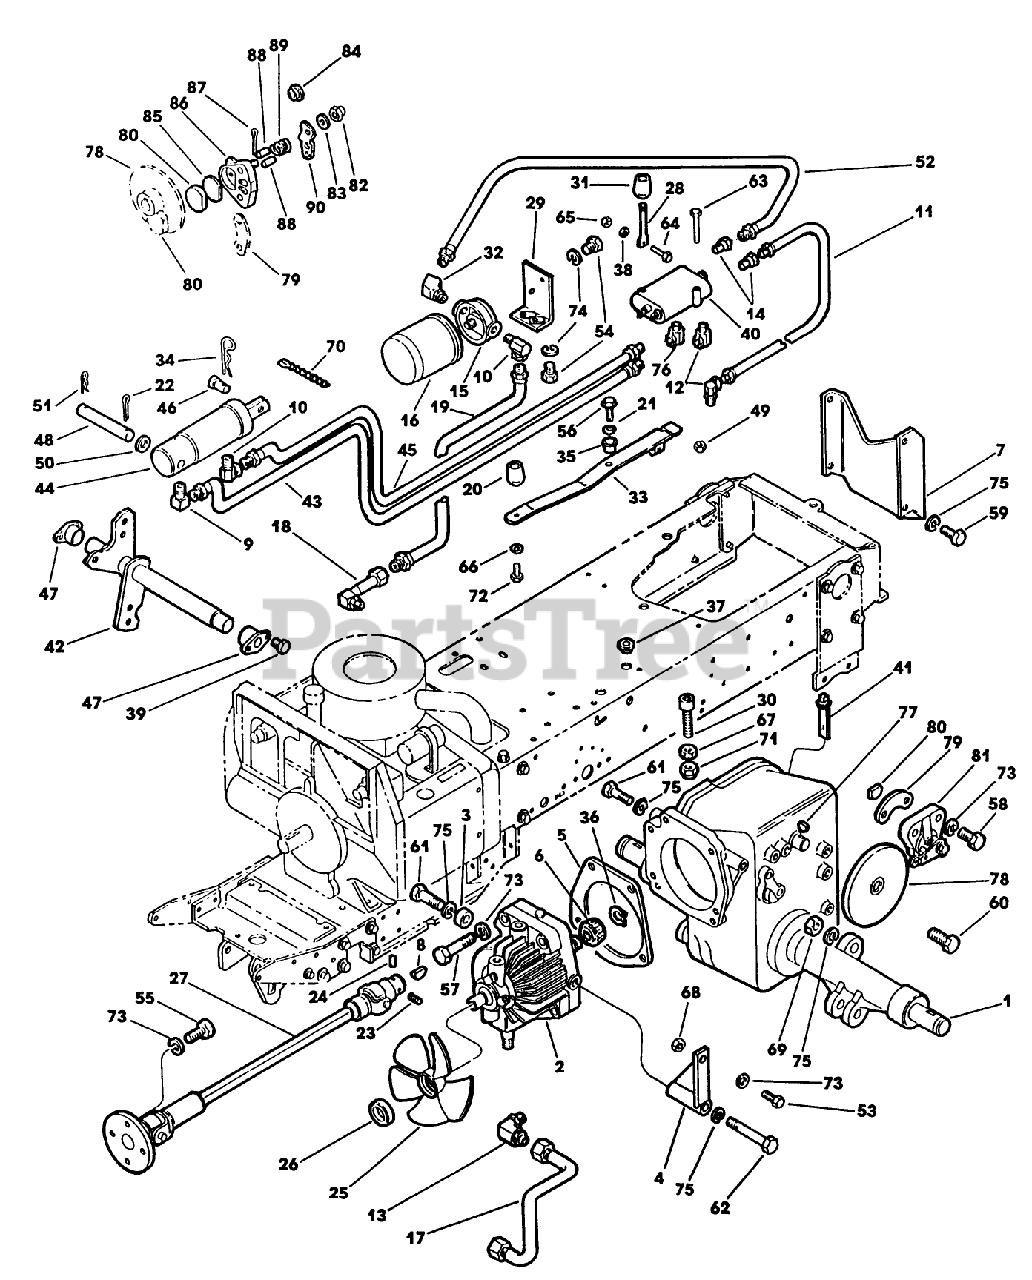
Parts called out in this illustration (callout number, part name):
5	GASKET
12	90 SWIVEL ELBOW
24	SET SCREW
25	FAN
27	SHAFT AY - DRIVE
34	PIN-HAIR
37	BUSHING
53	SCREW - HEX
56	SCREW-THD ROLL, HWH
62	SCREW-HH
65	NUT E
67	NUT
68	NUT
71	NUT-LOCK, CONE
73	WASHER
78	BRAKE AY-DISC T
80	PAD - BRAKE
